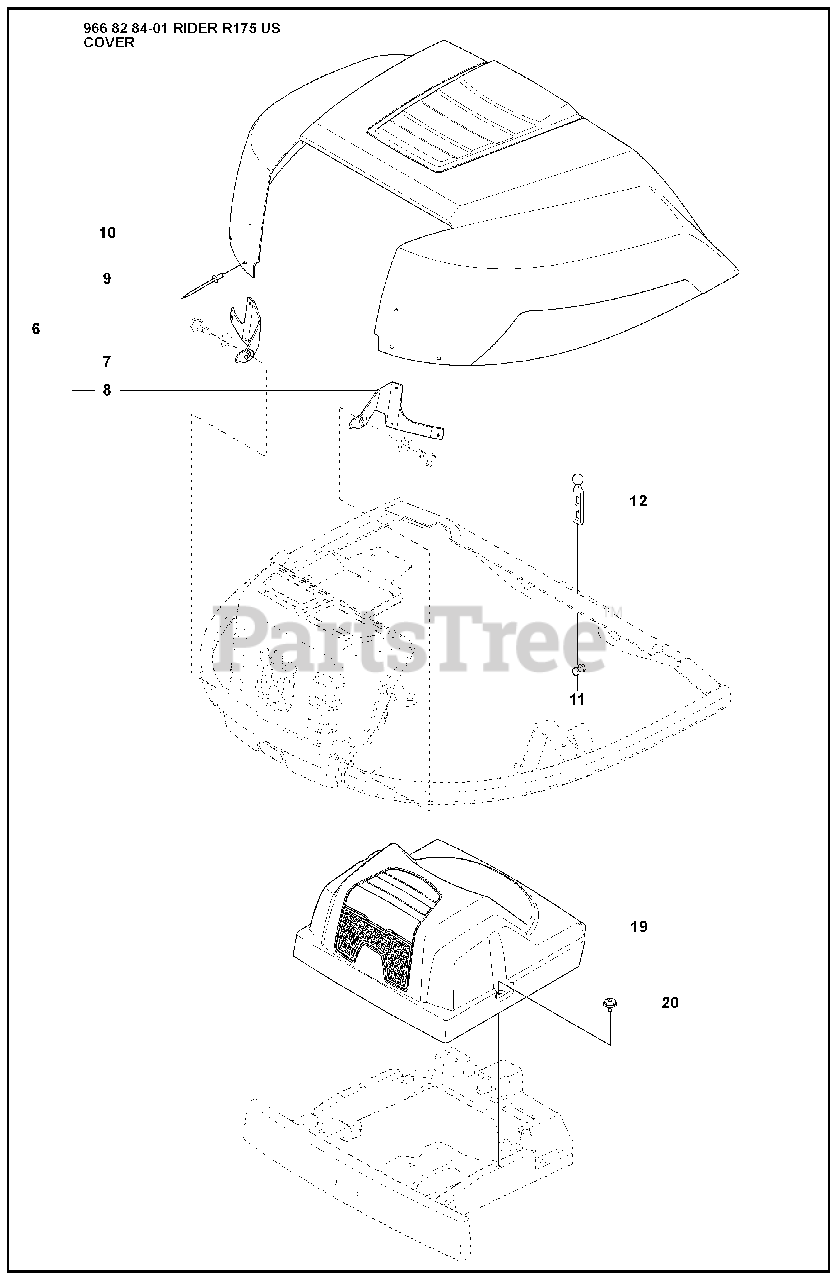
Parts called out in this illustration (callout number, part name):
6	ENGINE HOOD ASSY
7	HINGE
8	HINGE
10	ENGINE HOOD ASSY
12	SUPPORT STRAP
19	COVER
